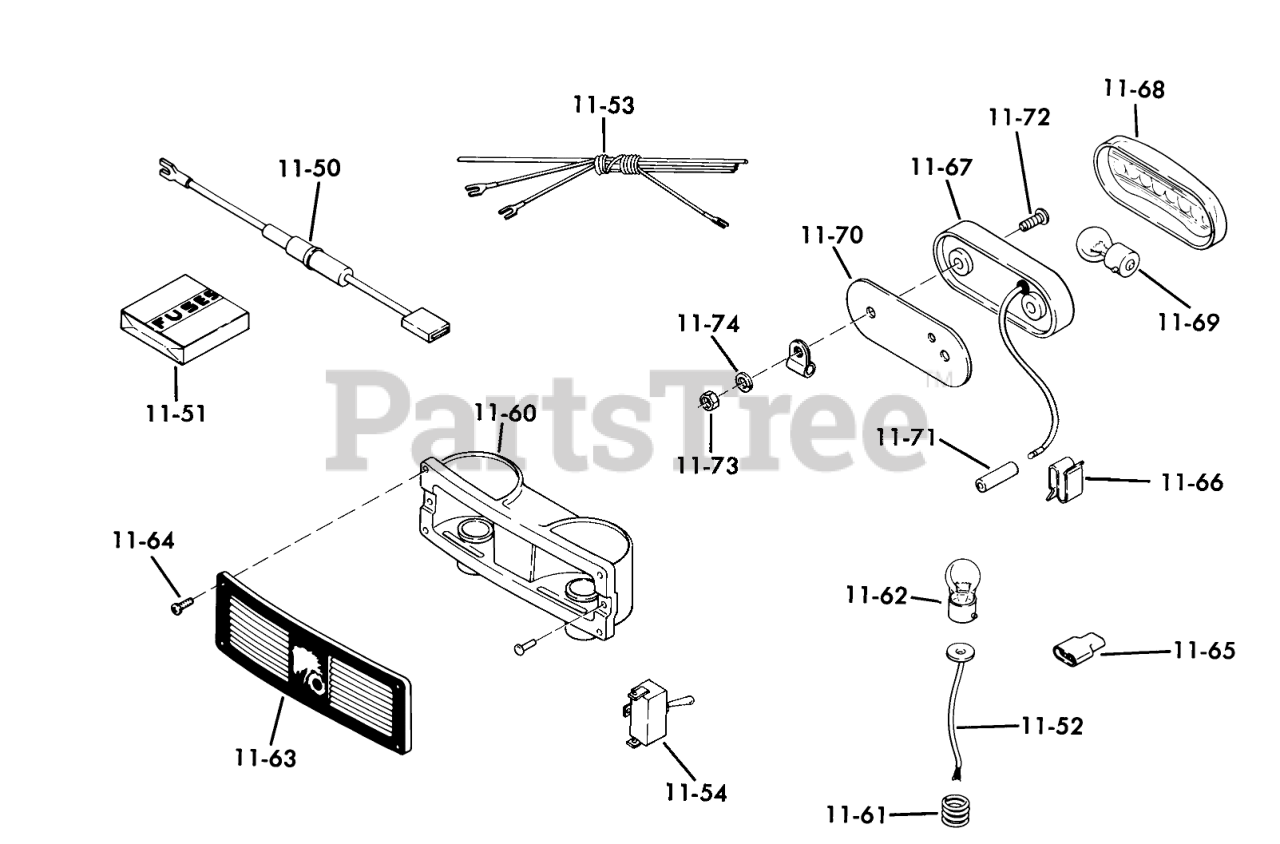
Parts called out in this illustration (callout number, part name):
11-50	ASSY FUSED CONNECTOR
11-52	WIRE ASSY
11-53	Wire Harness-Lights
11-54	SWITCH-LIGHTS
11-60	ASSY REFLECTOR HOUSI
11-61	SPRING
11-62	BULB
11-63	Lens
11-64	Pan HD Swage
11-65	CONNECTOR 3 WIRE
11-66	SPEED CLIP
11-67	Base
11-68	Lens
11-69	Bulb
11-70	Mounting Pad
11-71	CONNECTOR 2 WIRE
11-72	Screw
11-73	Nut
11-74	Lockwasher
